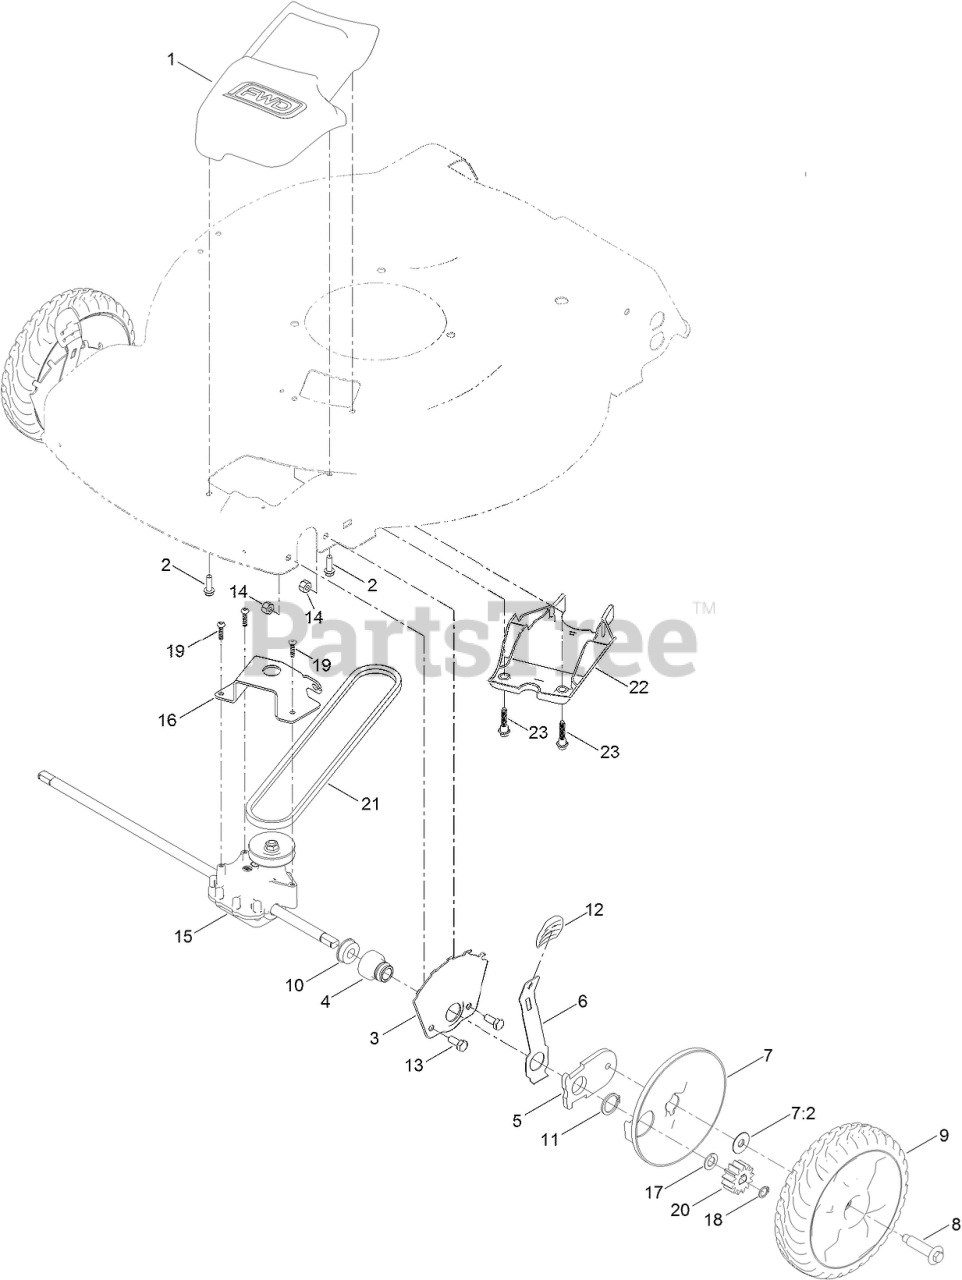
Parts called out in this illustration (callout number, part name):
1	COVER-BELT
2	SCREW-HWH
3	PLATE-HOC, FRONT
4	RETAINER-BEARING, HOC
5	ARM-PIVOT, FRONT
6	ARM-SPRING
7	WHEEL COVER ASM
7:2	WASHER-STEPPED
8	BOLT-SHOULDER
9	8 IN WHEEL ASM
10	BEARING-BALL
11	RING-RETAINING
12	KNOB-LEVER, HOC
13	SCREW-HH
14	NUT-LOCK, NI
15	TRANSMISSION
16	BRACKET-TRANSMISSION
17	WASHER-THRUST
18	RING-RETAINING
19	SCREW-PLASTITE
20	GEAR-PINION, 13T
21	V-BELT
22	COVER-BELT, FRONT (LOWER)
23	SCREW-SHOULDER, HHF
